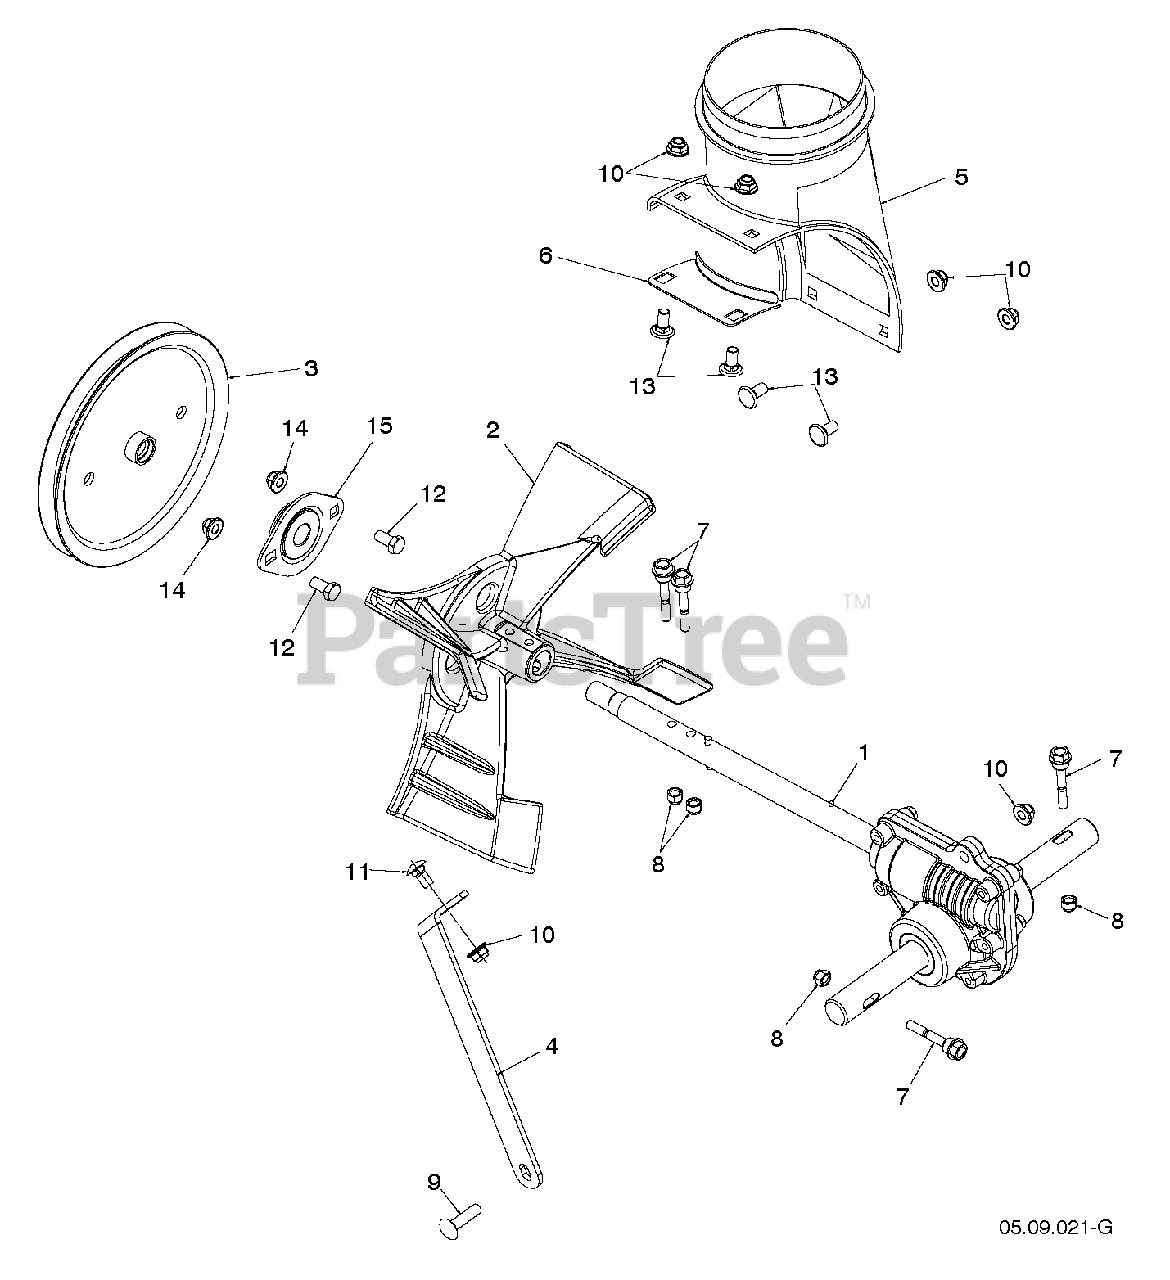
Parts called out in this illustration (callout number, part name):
1	GEAR BOX ASM CAST
2	IMPELLER CAST.IRON.12IN MS 417
3	PULLEY SCREW ON 7.9
4	SUPPORT.GEARBOX.LS.498
5	CHUTE.DISCHARGE.BASE
6	BRACKET, CORNER DISCHARGE
7	BOLT.1/4-20 X 1-13/16 SHEAR
8	LOCKNUT.NYLOC.1/4-20
9	BOLT.CARRIAGE.5/16-18
10	NUT HEX FLG NYLOCK BLK 5_16-1
11	BOLT CAR BLK 5/16-18 X 5/8
12	BOLT, HEX HEAD 5/16-18
13	BOLT CARR WAFER BLK 5_16-18 X
14	NUTNYLOK.FLRANGE.5/16-18
15	BEARING FLANGE
